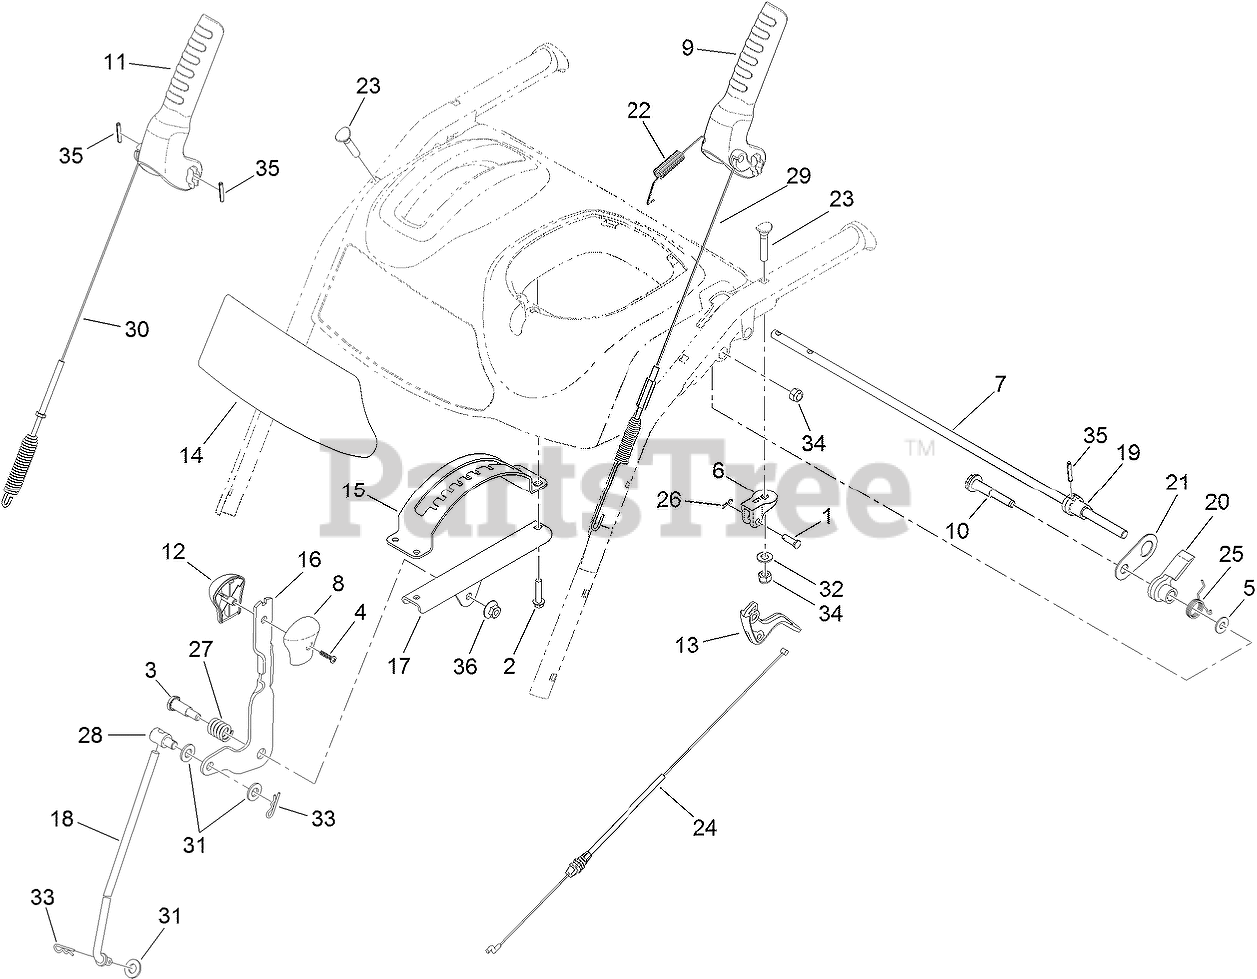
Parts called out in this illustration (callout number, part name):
1	PIN-CLEVIS
2	SCREW-PLASTITE
3	SCREW-SHOULDER
4	SCREW-PPH
5	WASHER-FLAT
6	MOUNT-CLUTCH, LEVER
7	ROD-LOCKOUT
8	KNOB-SHIFT, LH
9	LEVER-TRACTION
10	SCREW-SHOULDER
11	LEVER-AUGER
12	KNOB-SHIFT, RH
13	LEVER-CLUTCH
14	DECAL-CONTROL PANEL
15	GUIDE-SELECTOR, SPEED
16	SELECTOR-SPEED
17	MOUNT-SELECTOR, SPEED
18	ROD-SHIFT
19	CAM-LOCKOUT
20	LATCH-LOCKOUT
21	LINK-LOCKOUT
22	SPRING-TENSION
23	SCREW-HANDLE
24	CABLE-CLUTCH
25	SPRING-TORSION
26	PIN-HAIR
27	SPRING-COMPRESSION
28	TRUNNION-ROD
29	CABLE-TRACTION
30	CABLE-AUGER
31	WASHER-FLAT
32	WASHER-FLAT
33	PIN-COTTER
34	NUT-LOCK, NI
35	PIN-SPRING
36	NUT-HF
